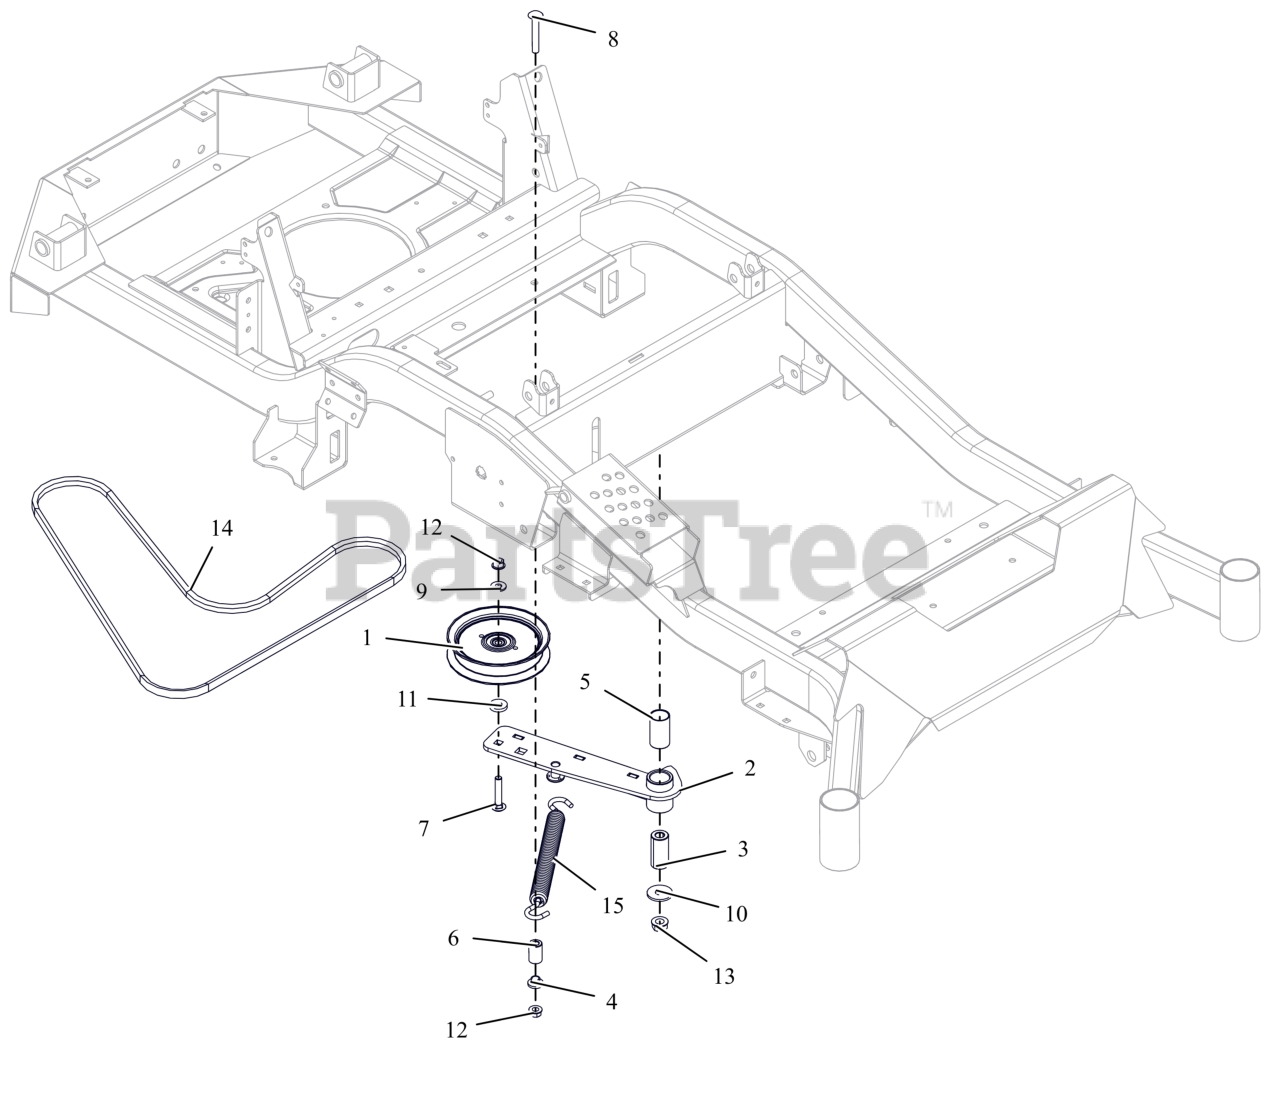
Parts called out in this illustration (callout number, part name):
1	IDLER, FLAT 5.00"
2	WLDMT, HYDRO DRIVE IDLER ARM (BLACK)
3	BSHG, SPCR .502X.997X2.03 PM
4	BSHG-FLG .385X.500X.875X.406
5	BSHG, 1.00X1.125X1.937
6	BUSHING, SLV .380X.750X1.190
7	BLT, RHSN .38-16X2.00 G5 ZCC
8	BLT, RHSSN.38-16X2.50 G5 ZCC
9	WSHR,FLT .375X.875X.083 ZCC
10	WSHR-FL-STL.511X1.44X.125ZC120
11	WSHR, FLT .406X1.00X.188 ZCC
12	NUT-LK-TOP-FLG .38-16 ZC120
13	NUT-LK-TOP-FLG .500-13 GF ZCC
14	V-BELT, 4L-WRAPPED
15	SPRING, EXTENSION
